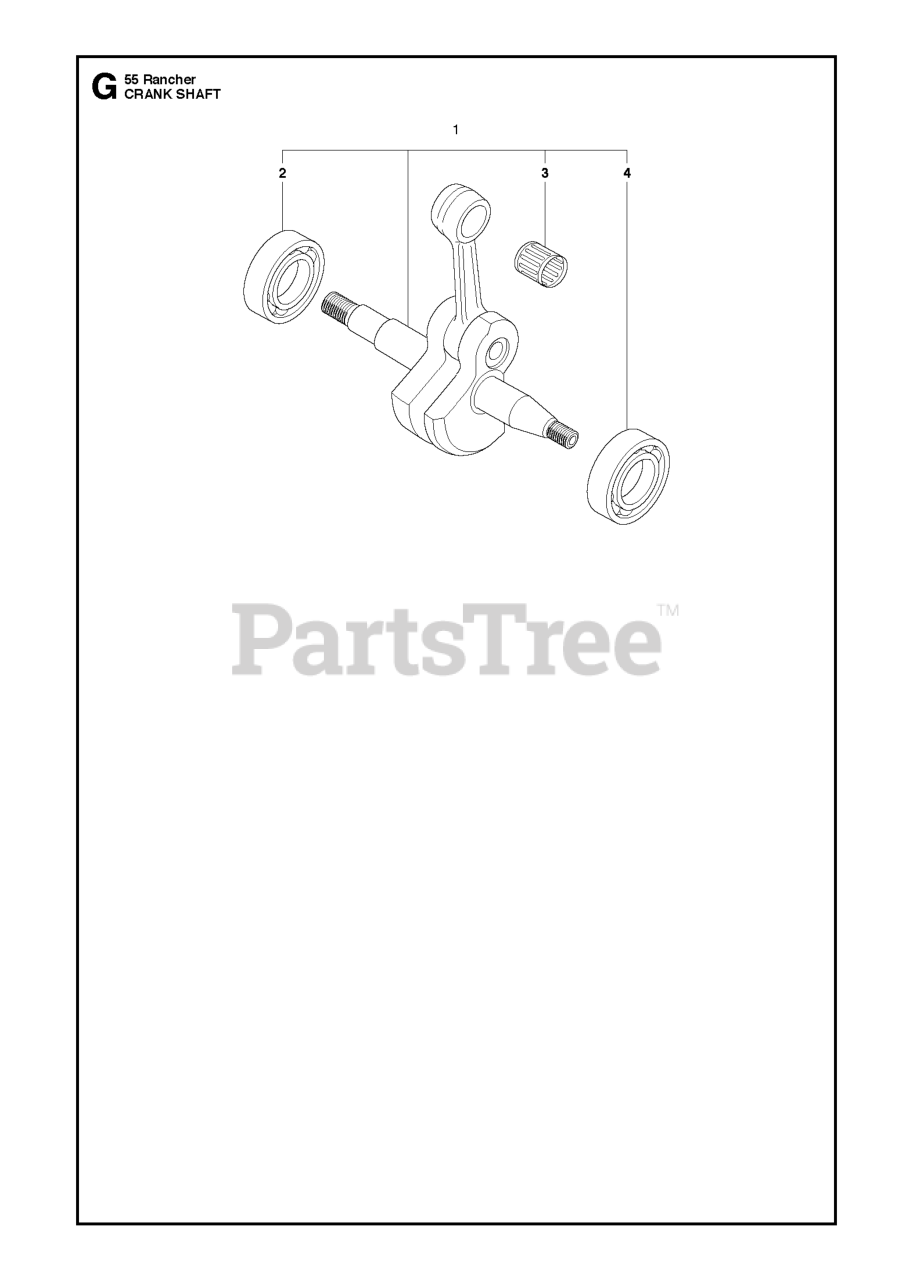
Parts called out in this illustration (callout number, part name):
1	CRANKSHAFT
2	BALL BEARING-6202-C3 SKF
3	SUPPORT BUSHING
4	BALL BEARING-6202-C3 SKF
